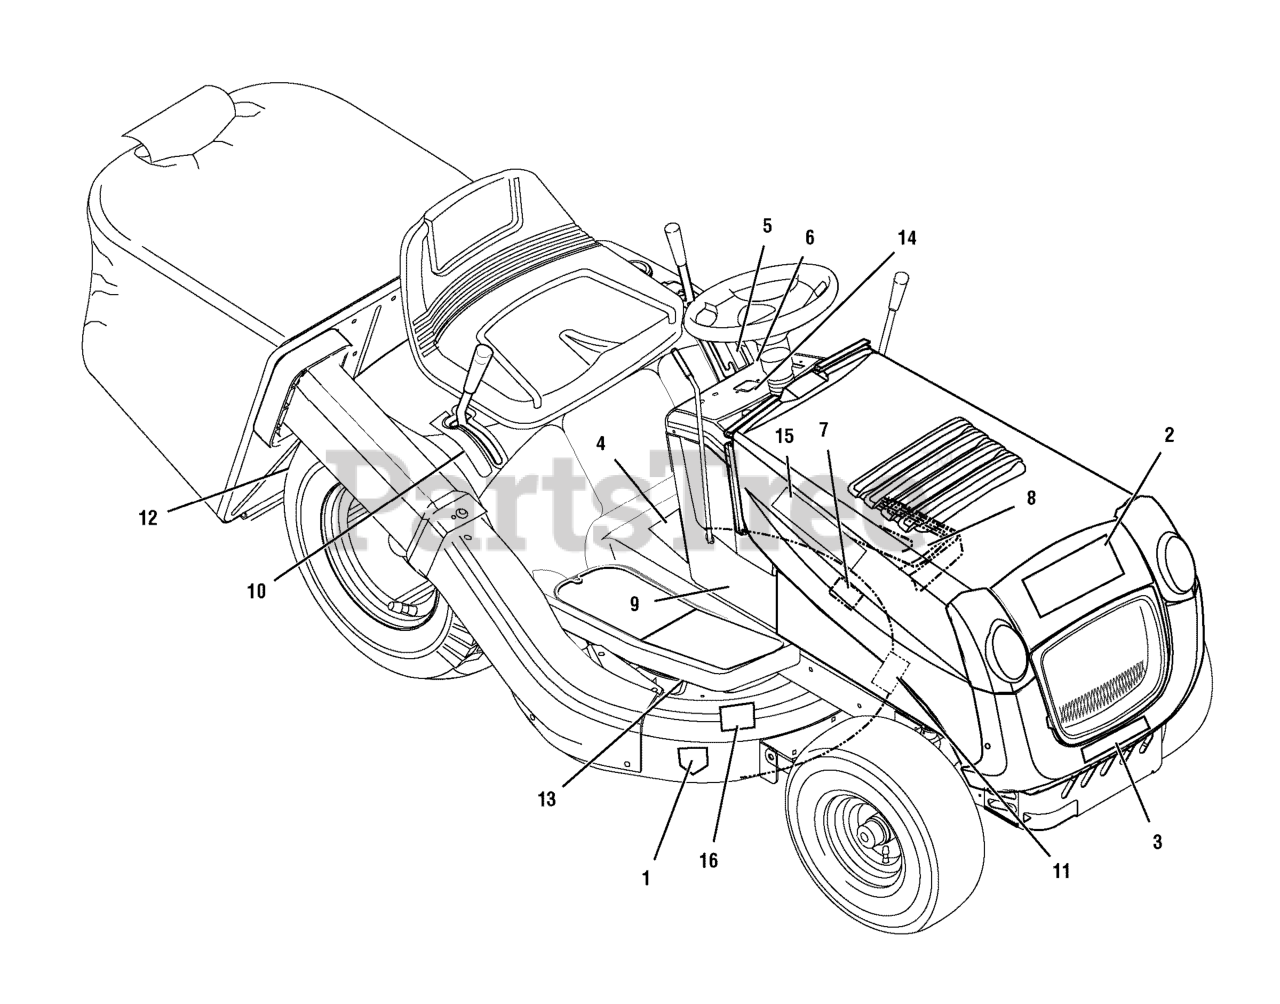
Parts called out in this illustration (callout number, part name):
1	DECAL, Cut Fingers Signal
2	DECAL, Hayter Emblem
3	DECAL, 13/30
4	DECAL, Warning Export
5	DECAL, 7 Position Cut Height
6	DECAL, Deck Level
7	DECAL, No Step Export
8	DECAL, Brake/Clutch Export
9	DECAL, B&S Logo
10	DECAL, 5 Speed
11	DECAL, Heat Shield Warning
12	DECAL, Warning Load Limit Export
13	DECAL, Warning Pinch Point
14	DECAL, Dash Symbols W1
15	DECAL, Hayter Heritage
16	DECAL, 100db Export
